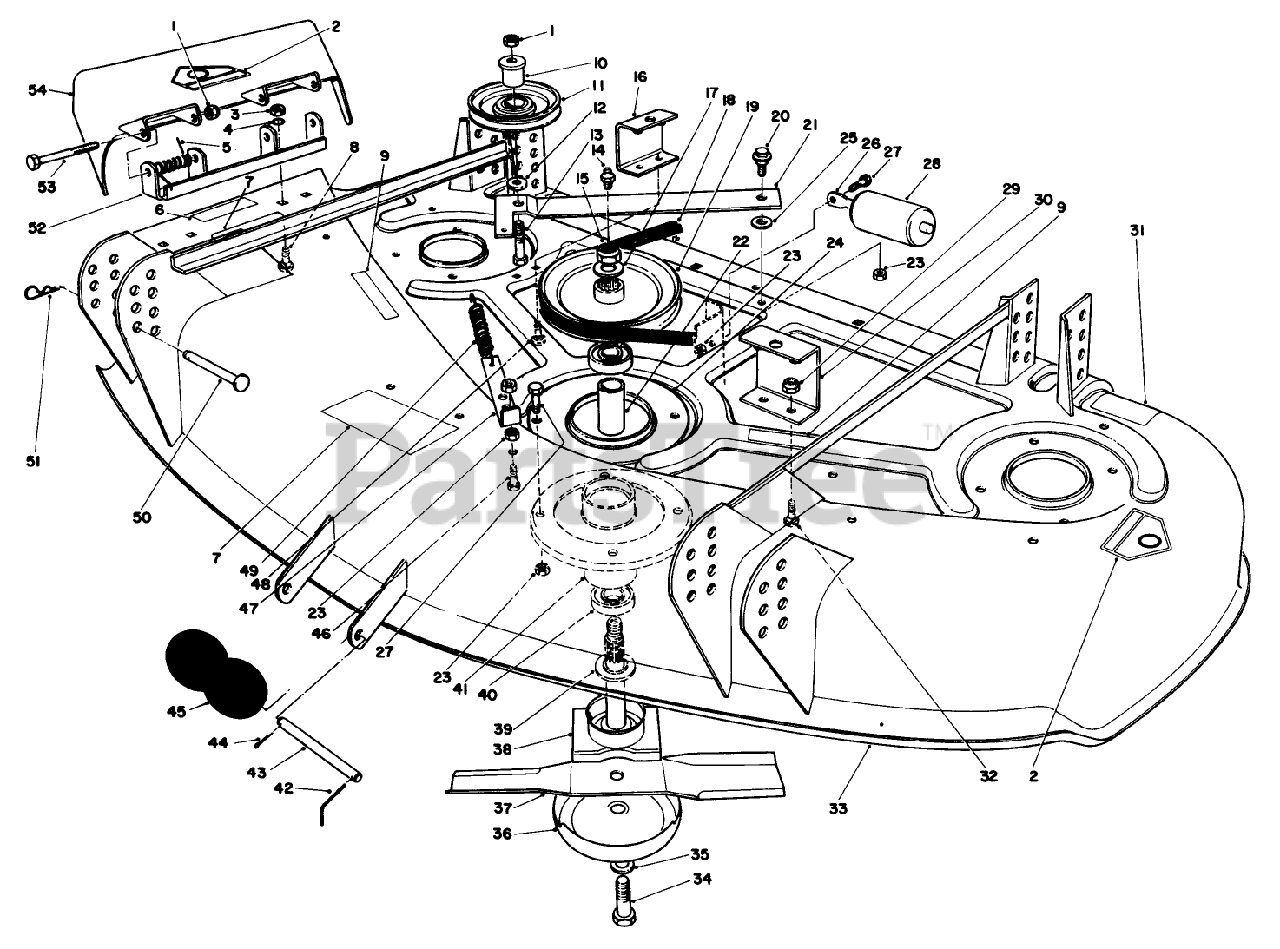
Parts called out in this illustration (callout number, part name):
1	NUT-HEX
2	DECAL-DANGER
3	NUT-HEX
4	Lockwasher
5	SPRING
6	DECAL-DANGER
7	DECAL-DANGER, THROWN OBJECT
8	SCREW-CARR
9	DECAL-DANGER
10	BUSHING-PULLEY
11	PULLEY-IDLER
12	WASHER-FLAT
13	SCREW-HH
14	FITTING-GREASE
15	NUT-HEX
16	Bracket-Cover RH
17	Washer
18	V-BELT-DECK
19	PULLEY-DECK
20	SCREW-SHOULDER
21	Lever-Deck
22	SPACER-BEARING
23	NUT-LOCK, CONE
24	DECK RING
25	WASHER
26	ROD-ROLLER
27	SCREW-HH
28	ROLLER-DECK
29	NUT-LOCK, NI
30	Bracket-Cover LH
31	DECAL-TORQUE
32	SCREW-CARR
33	44" Deck Assembly
34	SCREW-BLADE
35	WASHER-LOCK
36	Anti-Scalp Cup
37	Blade
38	Shaft-Spindle
39	SPACER-SPINDLE
40	BEARING-BALL
41	HOUSING-SPINDLE
42	PIN-SPECIAL
43	SHAFT-ROLLER
44	PIN-COTTER
45	ROLLER
46	SCREW-HH
47	Anchor-Deck Spring
48	SCREW-CARR
49	SPRING-EXTENSION, DECK
50	PIN-CLEVIS
51	PIN-HAIR
52	PIVOT BRKT WA R/B
53	SCREW-HH
54	Deflector-Grass
